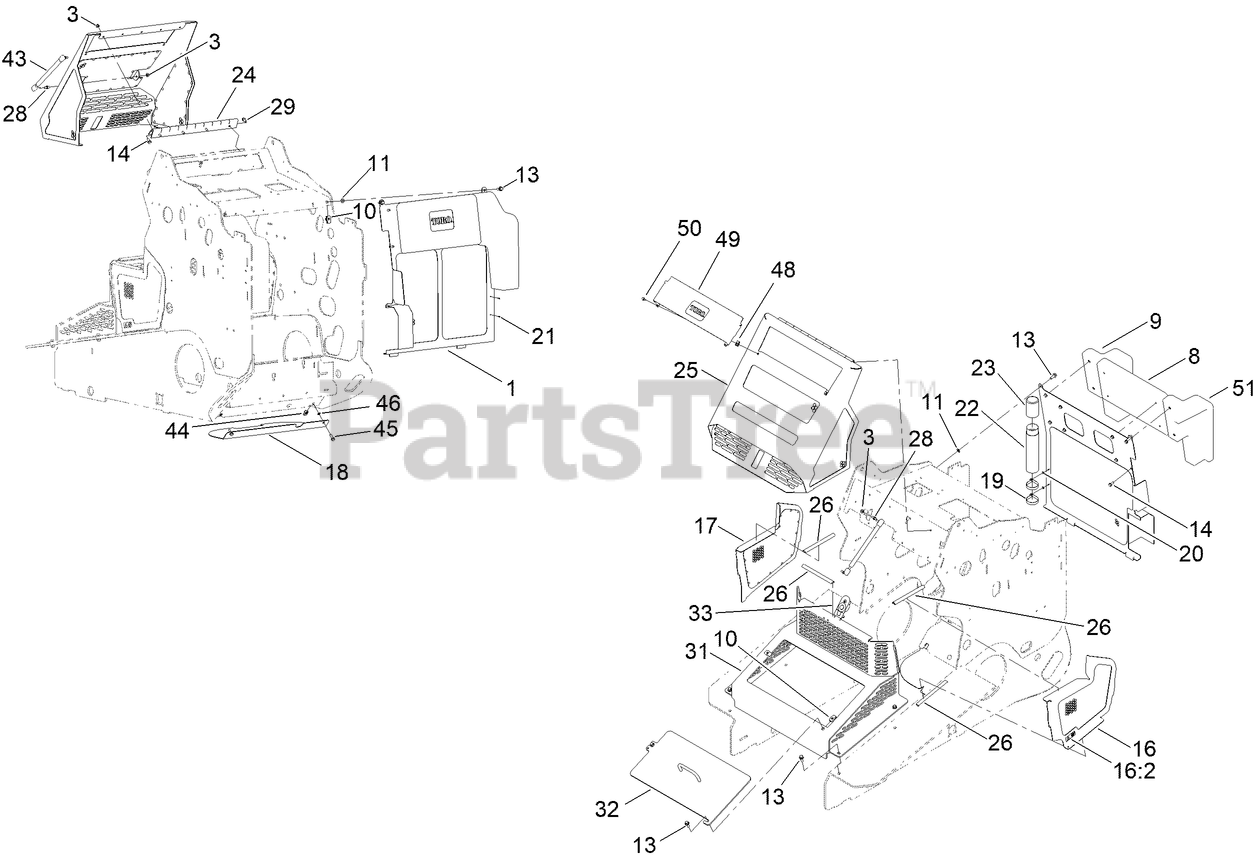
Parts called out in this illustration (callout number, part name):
1	COVER-REAR [BLACK]
3	NUT-HF, NI
8	CUSHION-PAD
9	CUSHION-PAD
10	NUT-TINNERMAN
11	NUT-PUSH
13	SCREW-HHF
14	SCREW-HHF
16:2	DECAL-SURFACE, HOT
17	COVER-SIDE, RH [BLACK]
18	COVER-BOTTOM
19	CLAMP-R
20	WASHER-BACK
21	RIVET-POP
22	TUBE-MANUAL
23	CAP-HOUSING
24	HINGE-HOOD
25	HOOD [BLACK]
26	SEAL-BULB
28	STUD-BALL
29	SCREW-HWHTF
31	COVER-FRONT [BLACK]
32	FRONT COVER ASM, [BLACK]
33	LATCH-COMPRESSION, LOCKING
43	SPRING-GAS
44	NUT-CLIP, U
45	SCREW-HHF
46	RING-RETAINING, BOLT
49	HOOD SCOOP ASM
50	SCREW-HWH
51	CUSHION-PAD
